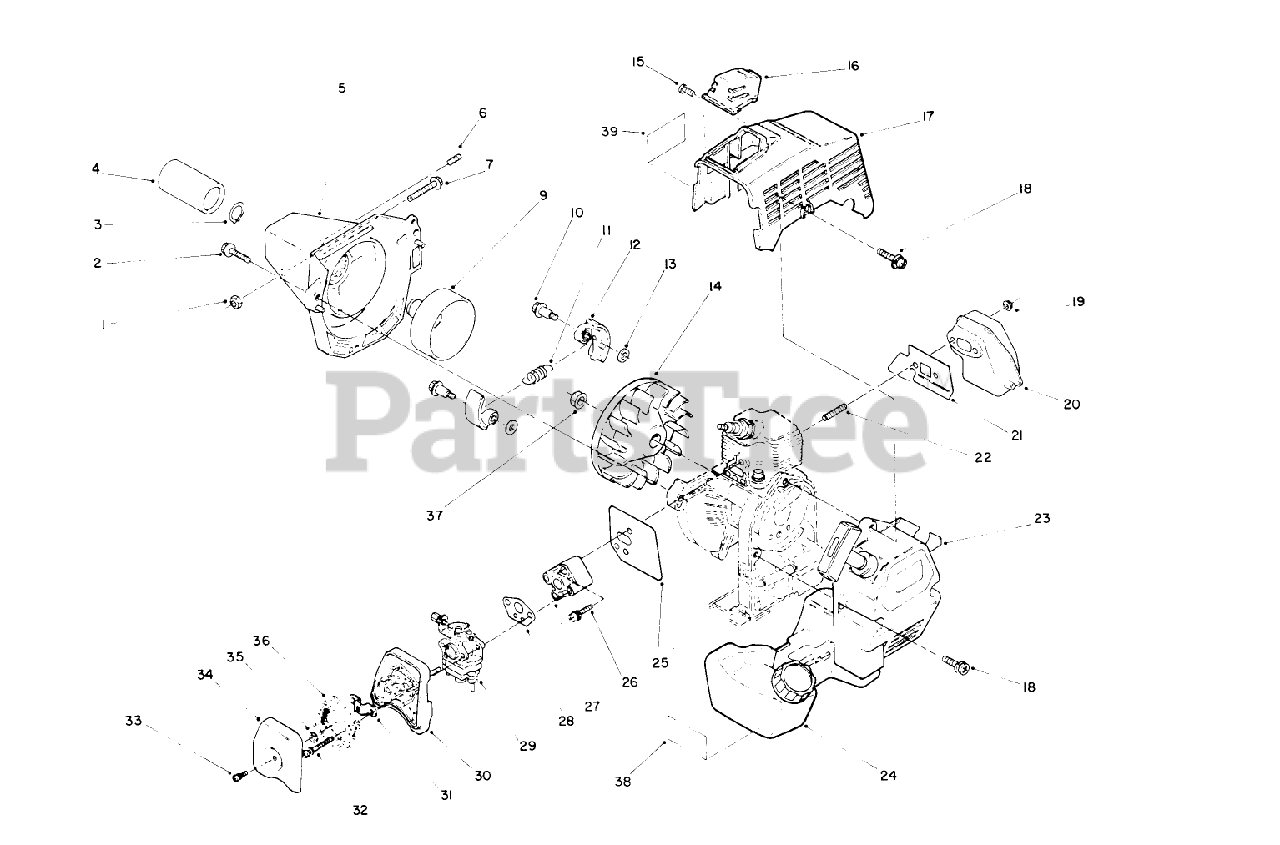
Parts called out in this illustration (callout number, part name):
1	DRIVE CASE
2	OIL SEAL
3	Gasket-Baffle
4	Screw
6	PLUG BOOT
7	Plug-Spark
8	CYLINDER
9	FLANGE BOLT
10	CYL GASKET
11	PISTON PIN CLIP
12	Pin-Piston
13	TOP RING
14	Piston (Incl. Ref. #11 & 12)
15	NEEDLE BEARING
16	STARTER CASE
17	Flywheel (Incl. Ref. #19 & 20)
19	RETURN SPRING
20	RATCHET
21	IGNITION COIL
23	LEAD WIRE
24	BOLT AND WASHER
25	GROMMET
26	BEARING
27	CRANKSHAFT ASSEMBLY
